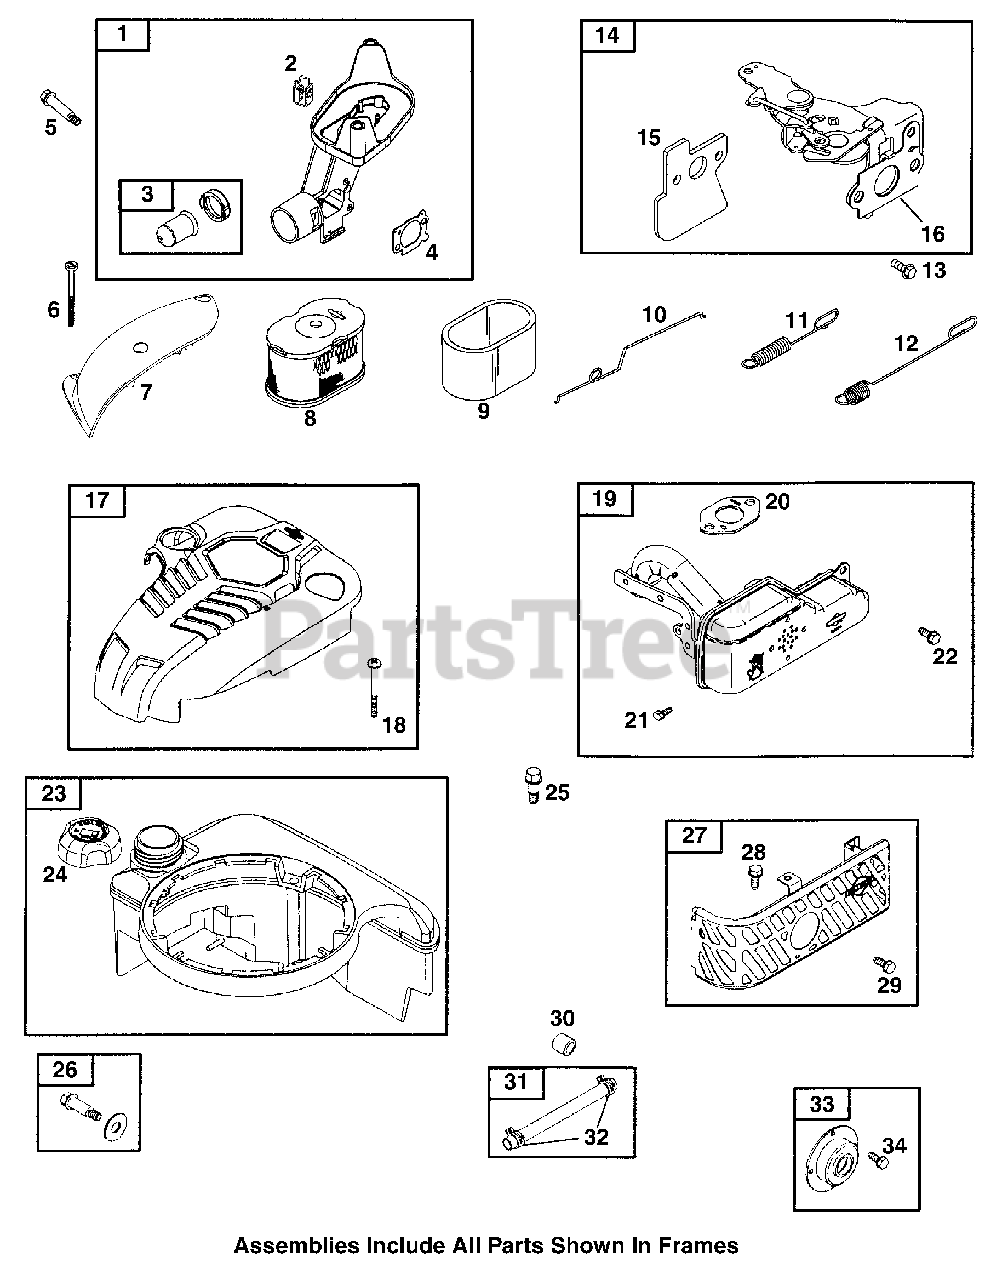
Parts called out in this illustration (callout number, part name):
1	A/C Primer Base
2	Casing Clamp Bracket
3	Carburetor Primer
4	Air Cleaner Gasket
5	Hex Screw
6	Shoulder Screw
7	Air Cleaner Cover
8	A/C Cartridge Filter
9	Pre-Cleaner Filter
10	Mechanical Governor Link
11	Governor Idle Spring
12	Governor Spring
14	Control Bracket
15	Carburetor Spacer
16	Intake Gasket
17	Blower Housing Cover
18	Phillips Screw
19	Exhaust Muffler
20	Exhaust Gasket
21	Hex Screw
22	Hex Screw
23	Fuel Tank
24	Fuel Tank Cap
25	Shoulder Screw
26	Screw/Washer Kit
27	Muffler Guard
28	Hex Screw
29	Hex Screw
30	Fuel Tank Spacer
31	Fuel Line
32	Hose Clamp
33	Muffler Deflector
34	Hex Screw
